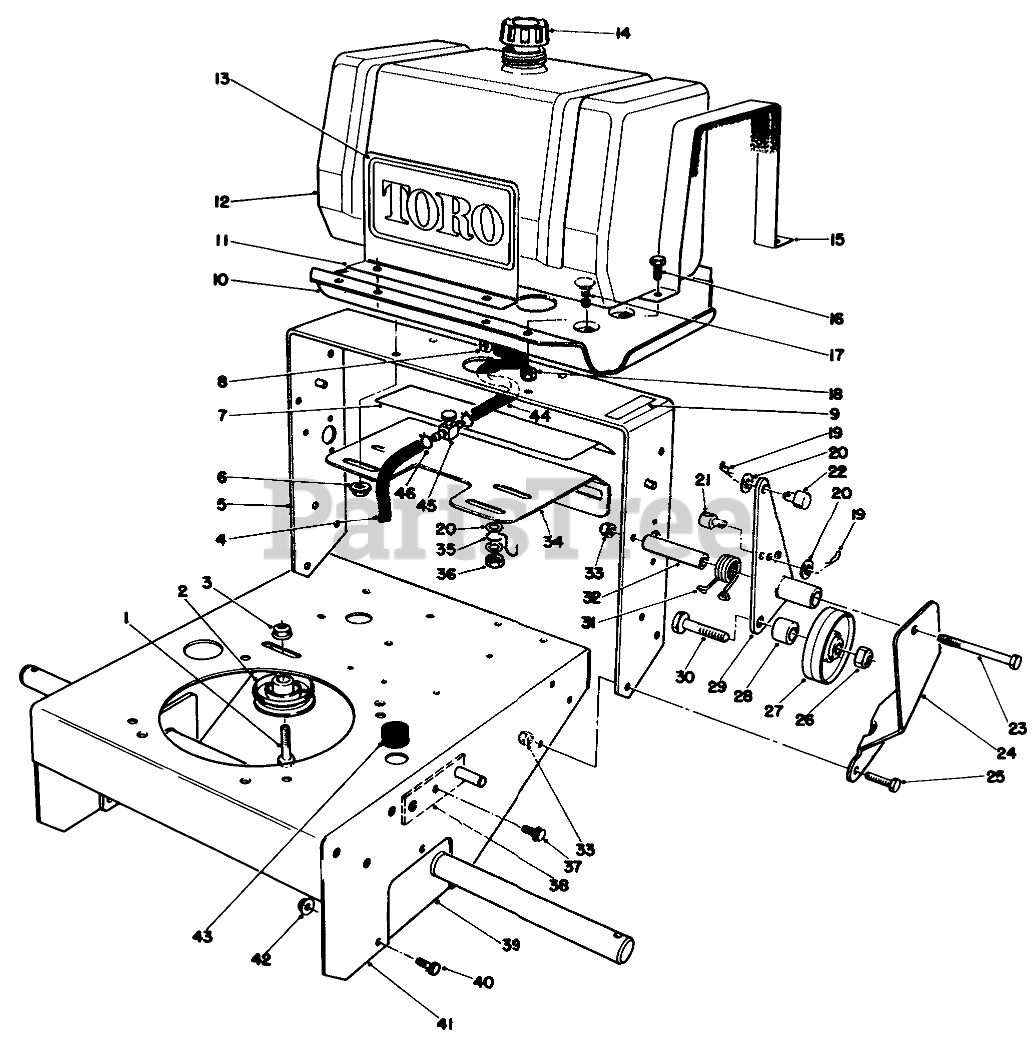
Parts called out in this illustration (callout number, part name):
1	SCREW-HH
2	PULLEY-IDLER
3	NUT-HF
4	HOSE-FUEL
5	REAR FRAME
6	NUT-HF
7	Decal-Ground Speed
8	CLAMP-HOSE
9	Decal-Fuel Shut Off
10	PLATE-FUEL TANK
11	DECAL-PLATE
12	TANK-FUEL
13	DECAL
14	GAS CAP ASM
15	STRAP ASM
16	SCREW-HH
17	SCREW-CARR
18	NUT-LOCK, NI
19	PIN-COTTER
20	WASHER-PLAIN
21	ROD FITTING
22	ROD FITTING
23	SCREW-HH
24	Bracket-LH
25	SCREW-HH
26	NUT-LOCK, NI
27	IdlerWheel
28	WHEEL IDLER SPACER
29	Bracket-Idler, LH
30	SCREW-LEVELER
31	SPRING-TORSION, LH
32	PIVOT-IDLER SPACER
33	NUT-LOCK, NI
34	Plate
35	GAS LINE CLIP
36	NUT-LOCK, NI
37	SCREW-HHF
38	PIVOT POST WA
39	AXLE PLATE WA R
40	SCREW-HHF
41	FRAME WA
42	NUT-LOCK, FLANGE
43	GROMMET
44	HOSE-FUEL
45	FUEL VALVE
46	Clamp
